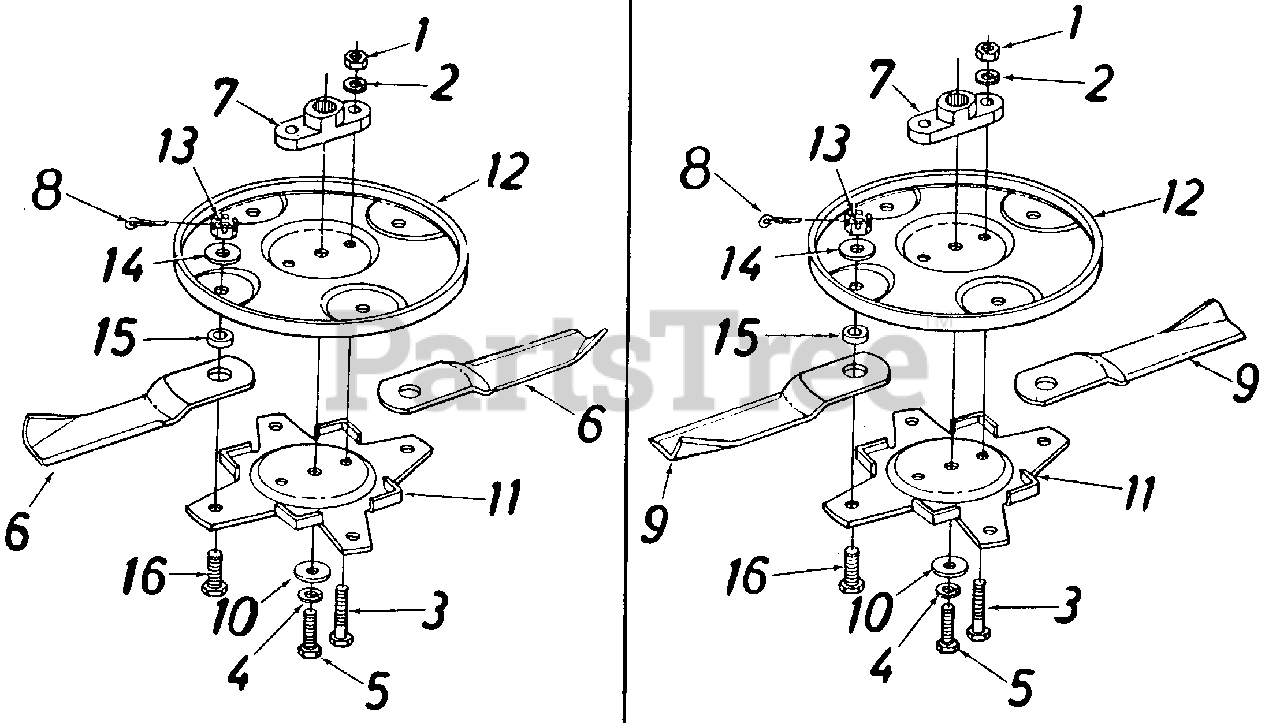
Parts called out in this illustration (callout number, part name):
1	Hex Nut 5/16-24 Thd.
2	L.-Wash. 5/16" I.D.
3	Hex BoltS/16-24 x 1.00" Lg.
4	L. Wash. 3/8" I.D., H.D.
5	Hex Bolt 3/8-24 x .88" Lg. (Grade 5)
6	Blade L.H. Rotation
7	Blade Adapter
8	Cottar Pin 3/32" Dia. x 1 00" Lg.
9	Blade-R.H. Rotation
13	Slotted Hex Nut 1/2-20Thd.
14	Fl.-Wash. .531" I.D. x 1.25" O.D.
15	Spacer
16	Shld. Scr. .50" Dia. x .36"
